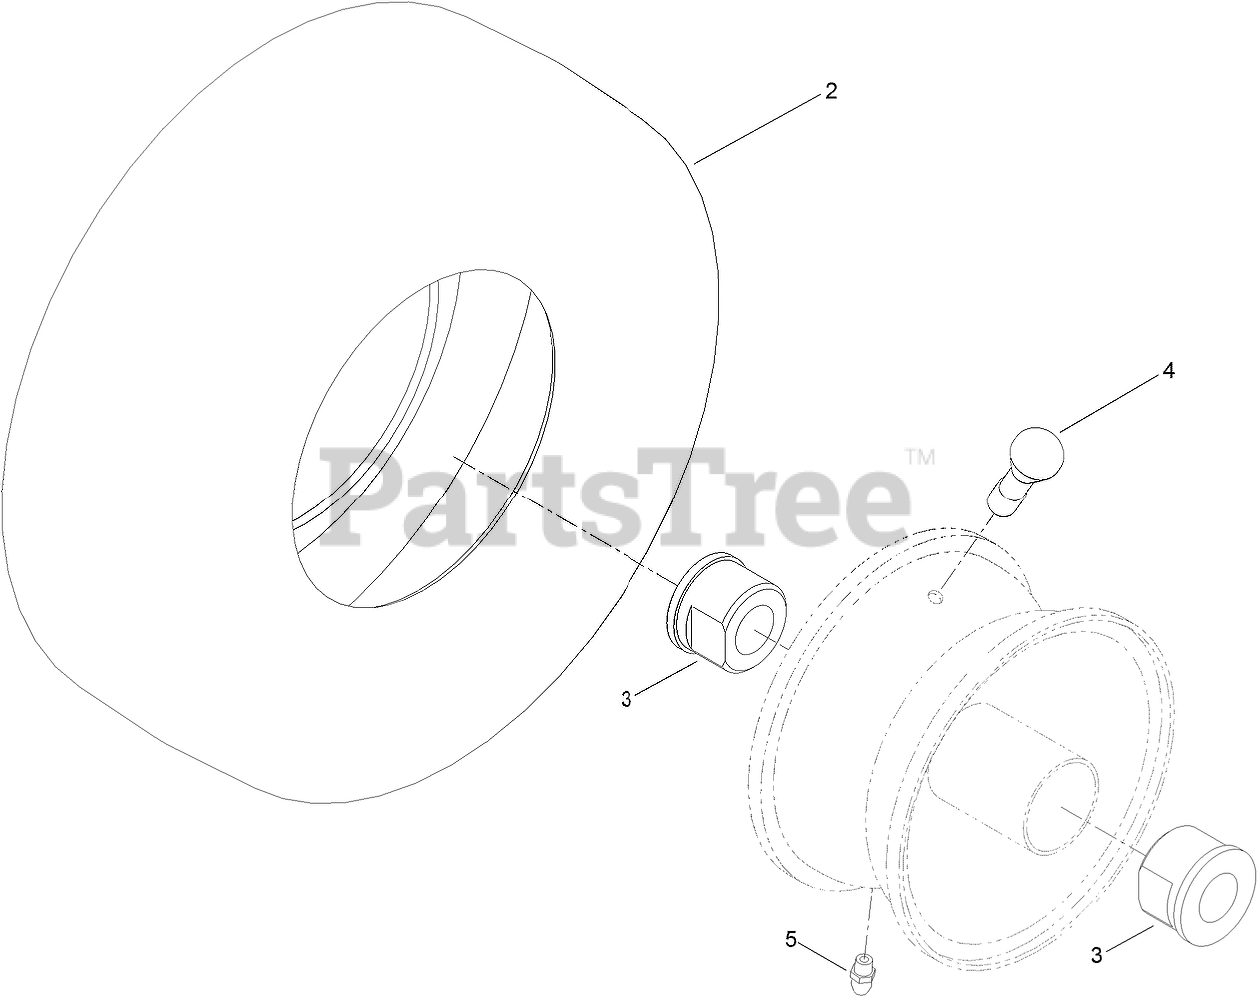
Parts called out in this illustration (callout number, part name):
3	BUSHING-FLANGE
4	STEM-VALVE
5	FITTING-GREASE
99	TUBE-INNER
